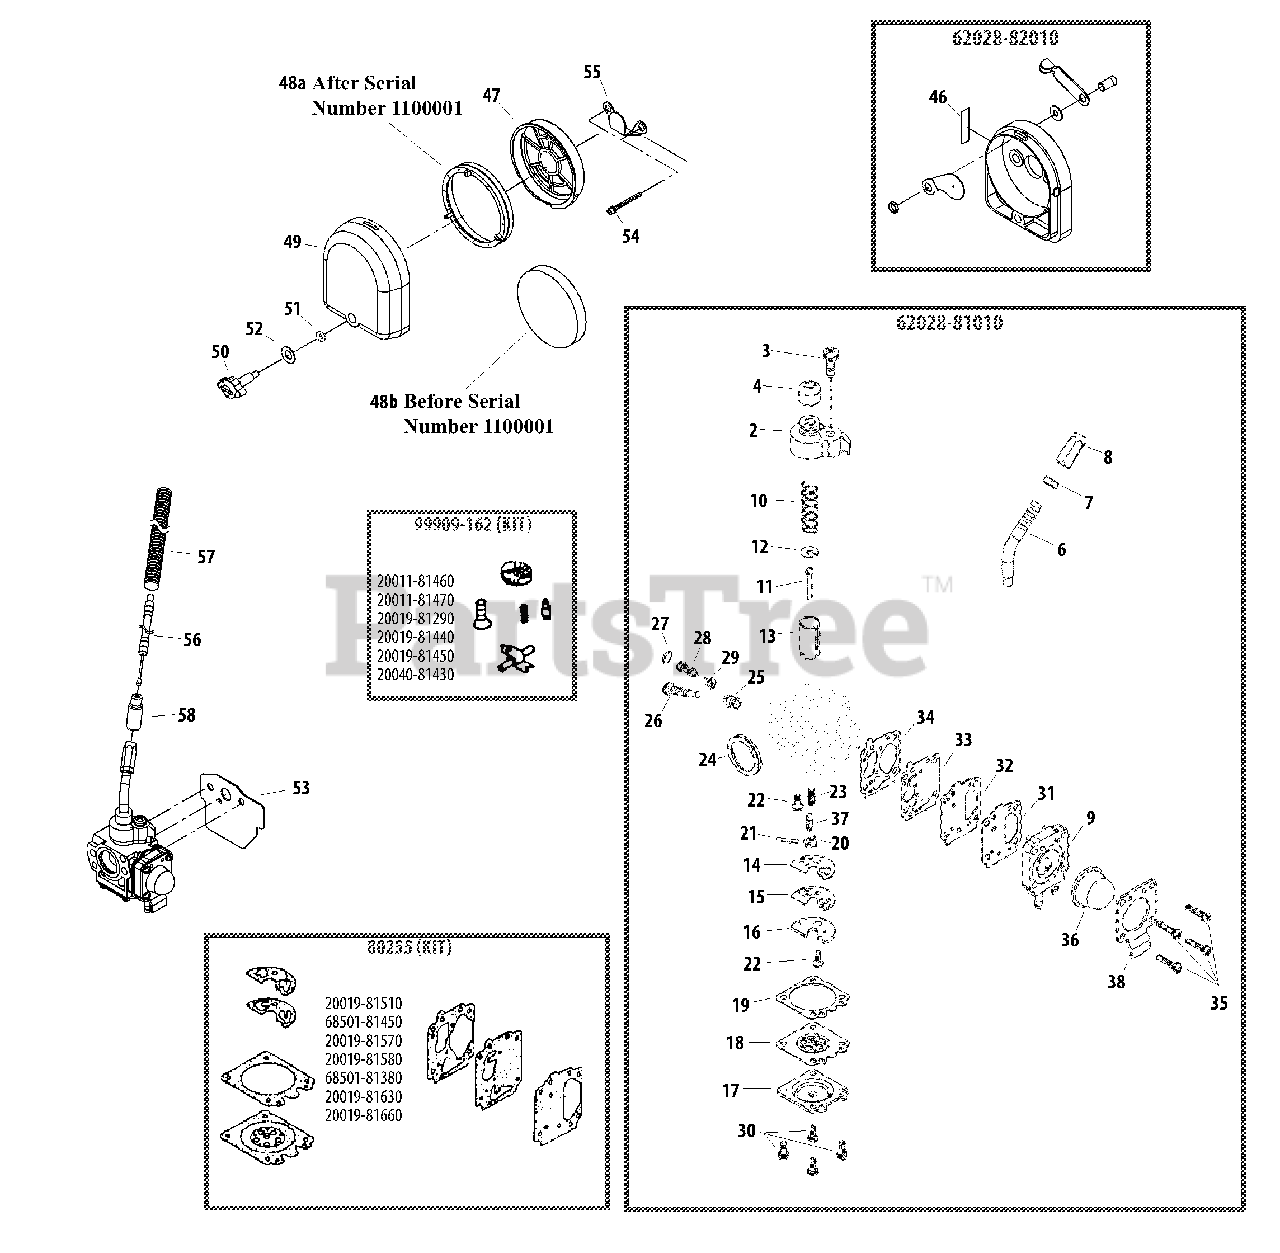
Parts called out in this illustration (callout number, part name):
2	CAP, CARBURETOR
3	SCREW - 5X15
4	GROMMET
6	GUIDE, CABLE
7	LOCKNUT
8	NUT, CABLE ADJUST
9	BASE, PURGE
10	SPRING, THROTTLE
11	NEEDLE, JET
12	RETAINER
13	VALVE, THROTTLE
14	GASKET
15	VALVE, CHECK
16	PLATE
17	COVER, DIAPHRAGM
18	DIAPHRAGM, METERING
19	GASKET, METERING
20	LEVER, METERING
21	PIN, METERING LEVER
22	SCREW, METERING LEVER PIN
23	SPRING
24	SEAL
25	SPRING
26	SCREW, IDLE ADJUST
27	PLATE
28	SCREW, ADJUST
30	SCREW
31	GASKET, PUMP
32	PLATE, PUMP
33	DIAPHRAGM, PUMP
34	GASKET, PUMP
35	SCREW - 3X14
36	BULB, PURGE
37	VALVE, INLET NEEDLE
38	COVER, PUMP
46	LABEL - CHOKE
47	BRACKET, FILTER -- REAR
48A	FILTER, AIR - HEAVY DUTY
48B	FILTER, AIR - FOAM
49	COVER, AIR FILTER
50	THUMBSCREW
51	O-RING
52	WASHER - CONICAL
53	GASKET, INTAKE
54	SCREW - 5X50
55	BRACKET
56	CABLE, THROTTLE
57	TUBE
58	CAP, DUST
20019-81290	STRAINER
62028-81010	CARBURETOR
62028-82010	AIR FILTER CASE ASSY
80255	DIAPHRAGM/GASKET KIT
99909-162	REPAIR KIT
